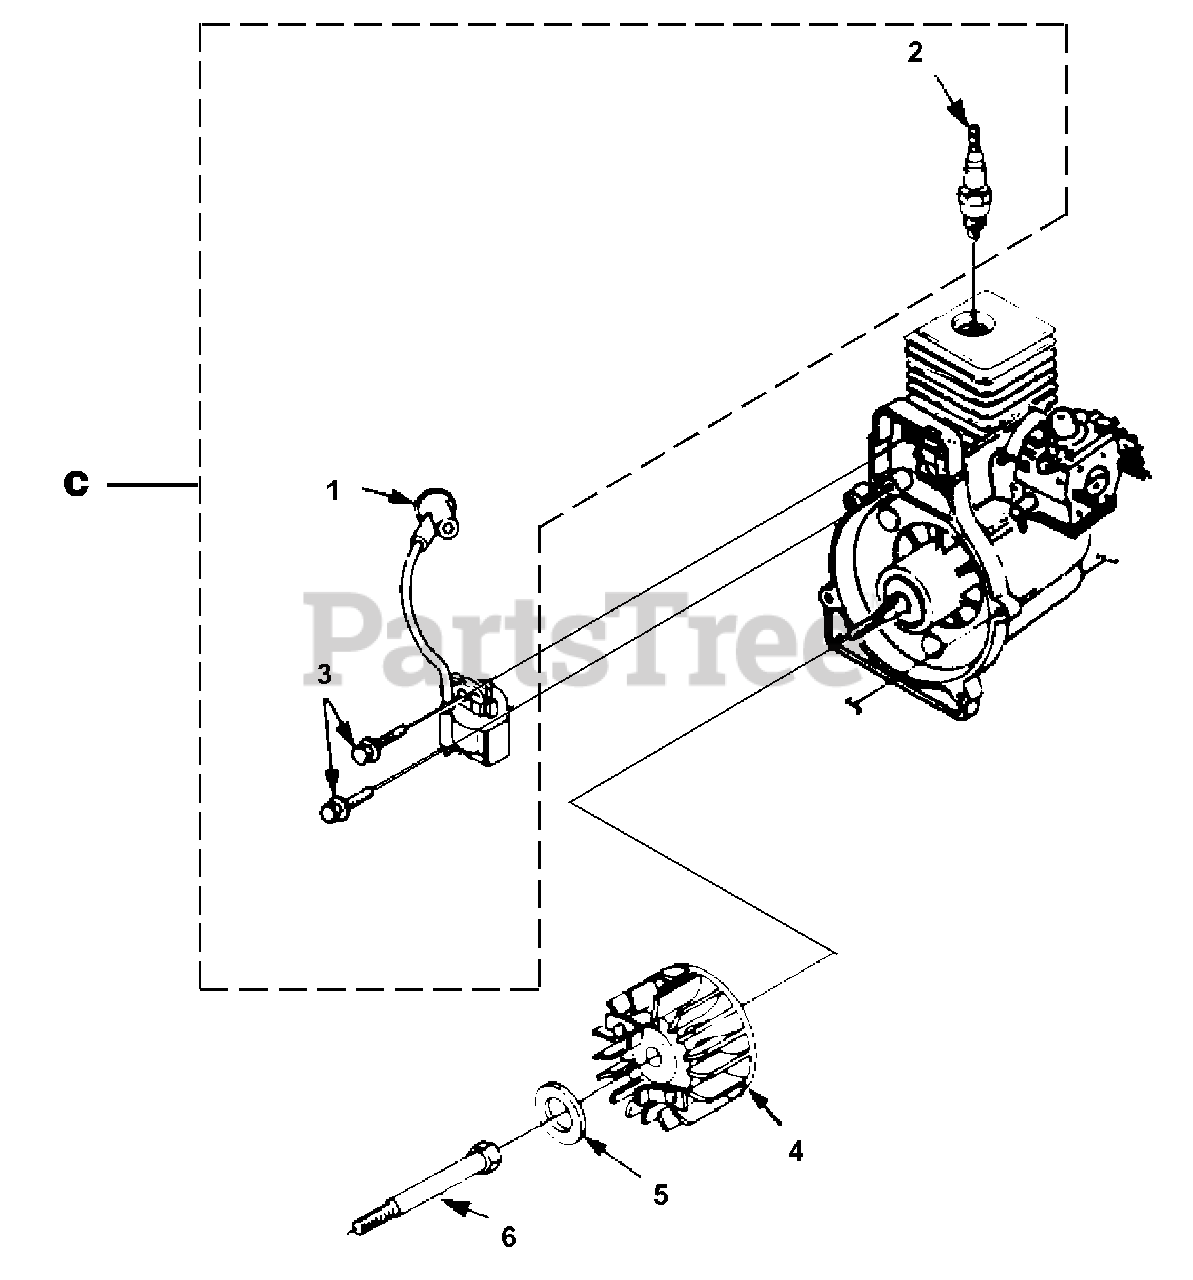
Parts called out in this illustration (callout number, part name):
1	TERMINAL-Hi Tension
2	SPARK PLUG (RDJ-7Y)
3	SCREW-Thread Form. (8-32 X 1")
4	ROTOR & STARTER PAWL KIT
5	WASHER-Flat
6	EXTENSION-Shaft
C	IGNITION KIT
